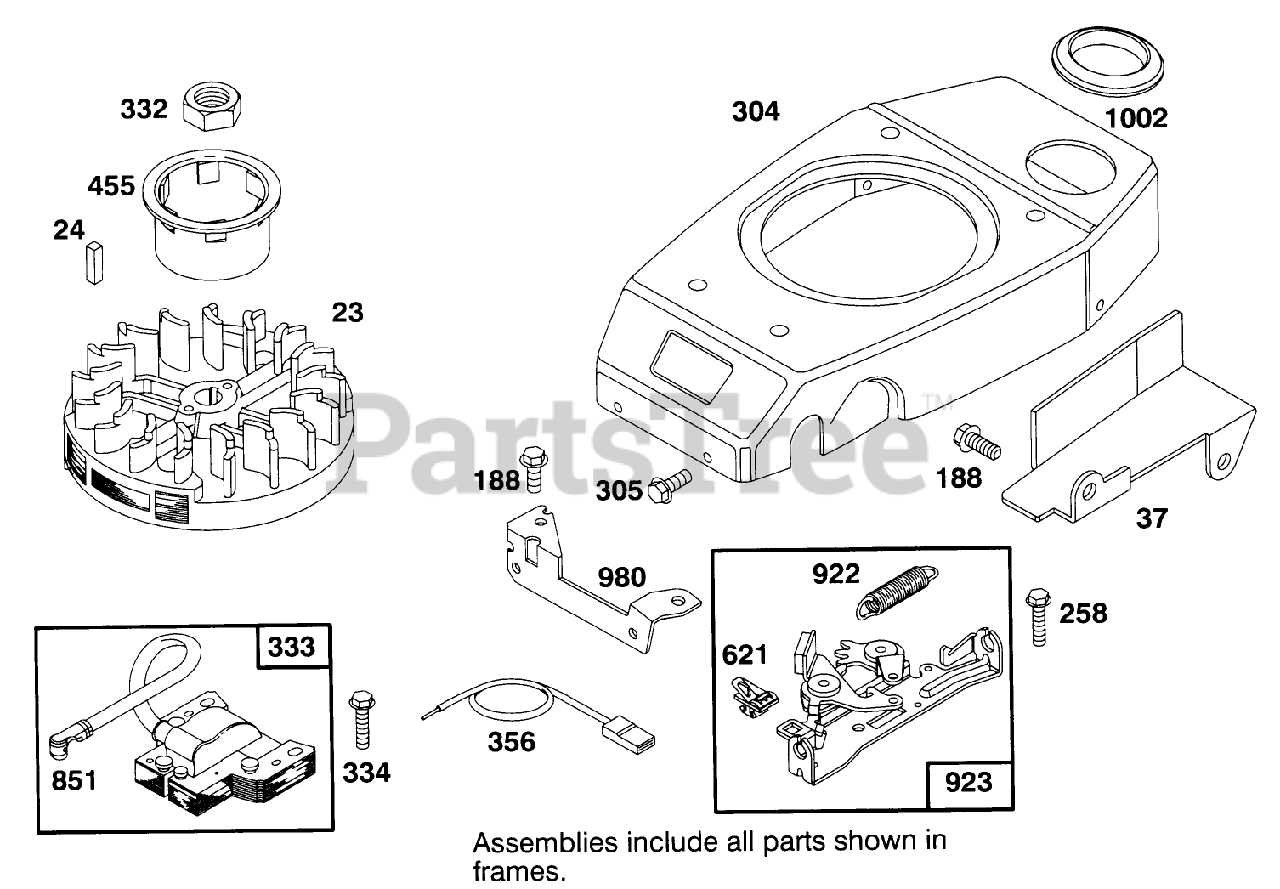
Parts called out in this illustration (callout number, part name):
24	KEY - FLYWHEEL
37	GUARD - FLYWHEEL
304	HOUSING - BLOWER
305	SCREW - HEX HEAD
332	NUT - HEXAGON
334	SCREW - SEM
356	WIRE - GROUND
621	STOP SWITCH
980	BRACKET-BLOWER HSG
